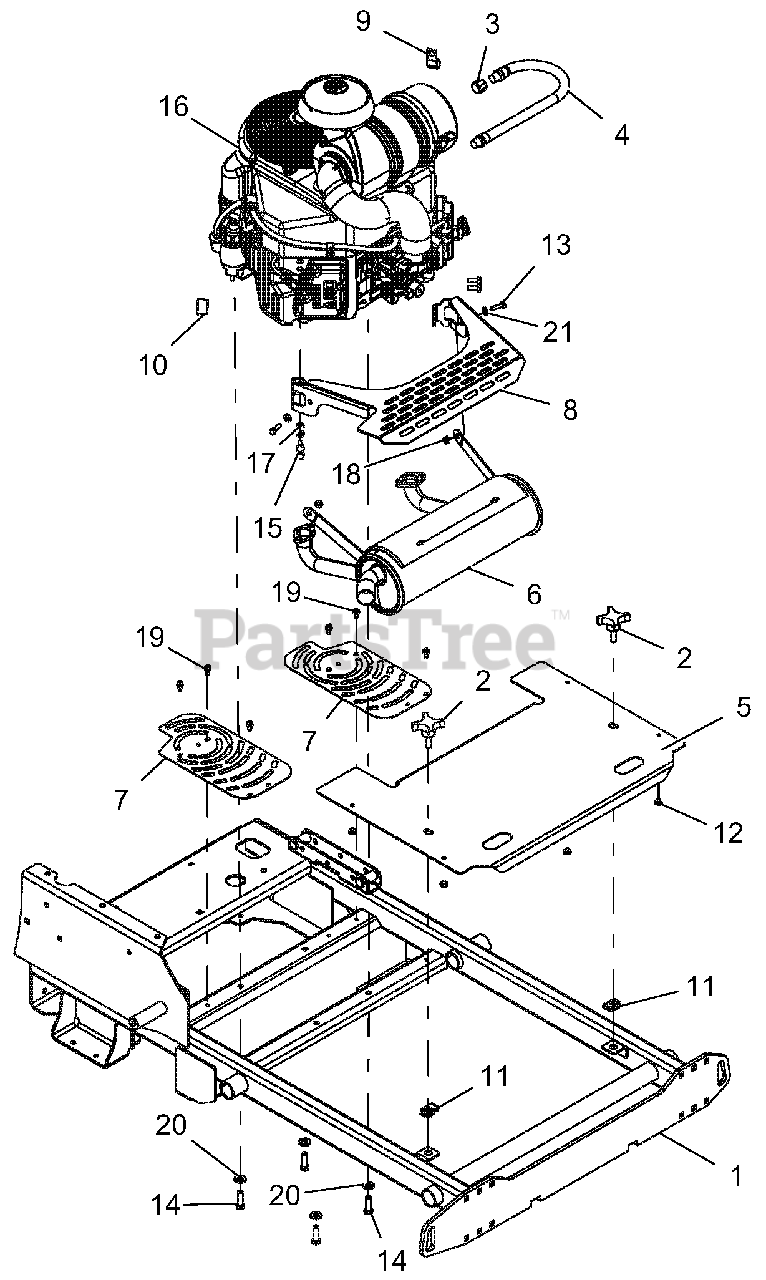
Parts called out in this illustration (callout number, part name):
1	WLDMT, FRAME PROSTANCE
2	KNOB, 3/8 X 1.25 - 4 PRONG
3	PIPE, CAP 3/8 NPT FEMALE
4	DRAIN, M20 OIL
5	SHIELD, FRONT PRO-STANCE-RED
6	EXHAUST, KAWASAKI PROSTANCE
7	GUARD, FAN
8	SHIELD, MUFFLER-BLACK
10	CLAMP, CUSHIONED STEEL REV
11	NUT, RTNR .375-16X.37
12	BUMPER GROMMET .125 X .25 REV
13	BLT-HEX .25-20X1.00 GR5 YWZC
14	BLT-HEX .38-16X1.25 GR5 YWZC NYTORQ
15	@BLT-HEX M8-1.25X20 YWZC
16	ENGINE, KAWASAKI FX730
17	WSHR-LK .31X.078 REG YWZC
18	NUT-LK-NYL-FLG .25-20 YWZC
19	SCR-TAP .25-20X.50 HWH TR YWZ
20	WSHR, 3/8" SPRING DISC
21	WSHR-FL-STL.281X.62X.065 YWZC
